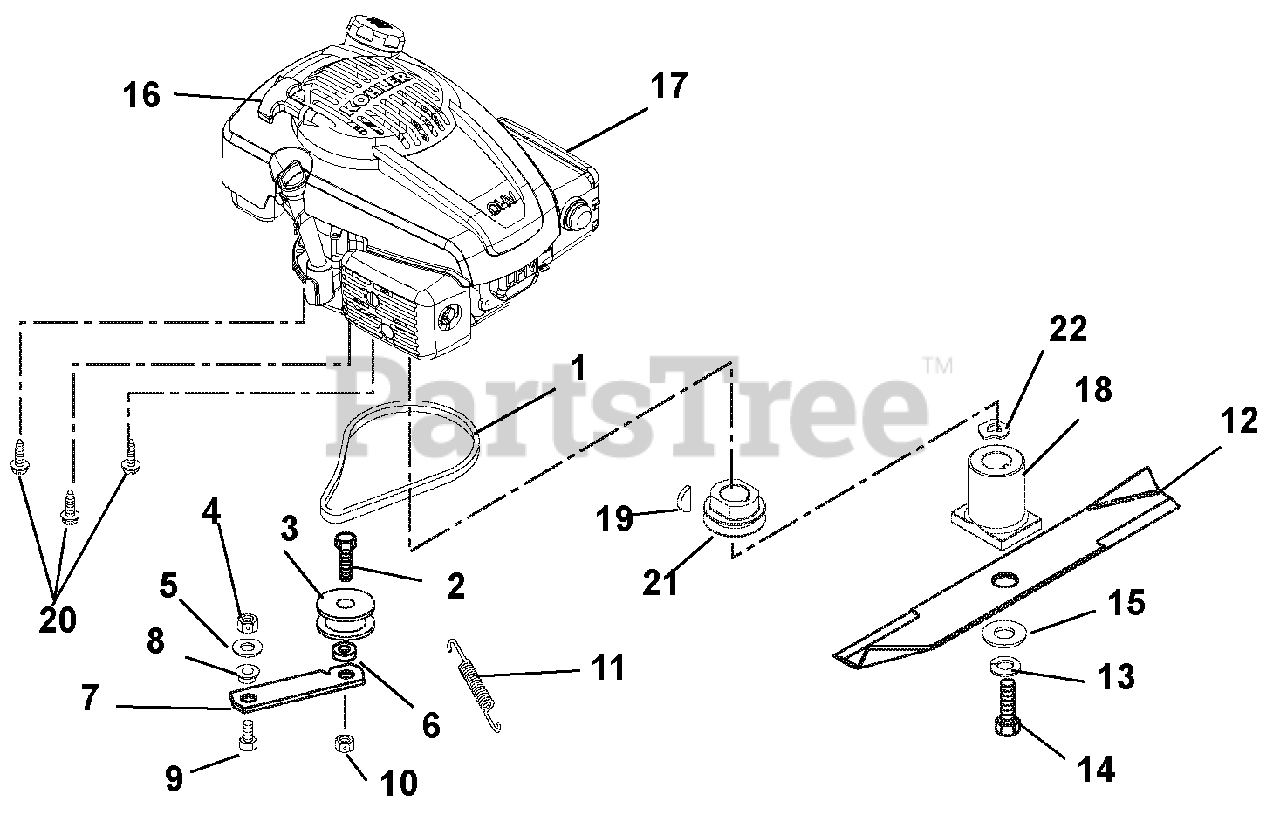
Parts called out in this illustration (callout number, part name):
1	V-Belt 3L Section
2	Bolt, Hex .44-14 x 1.50 Grade 5
3	Idler, Flat 1.75 x .47
4	Nut, Locking Center .31 -18
5	Washer, Flat Steel .344 x .688 x .065
6	Bushing, Sleeve .469 x .75 x .43
7	Idler Arm
8	Bushing, Flange .325 x .501 x .250 x 1.120
9	Bolt, Hex .31-18 x .75 Grade 5
10	Nut, Locking Center .44-14
11	Spring, Tension .043 x .44 x 3.31
12	Blade, 21" Mower
13	Washer, Locking .38 x .094
14	Bolt, Hex .38-24 x 2.00 Grade 8
15	Washer, Flat Steel .390 x 1.50 x .125
16	Recoil Start Handle
17	Engine, Kohler XT-7 (911260, 262, 264)
17	Engine, Kohler XT-7 CARB (911261, 263, 265)
17	Engine, Kawasaki 6.0hp Consumer (911136, 137)
18	Adapter, Blade
19	Key, Woodruff .156 x .625 x .25 SAE #6 (911136, 137, 262, 263, 264, 265)
20	Screw, Tapping .38-16 x 1.00 Hex Washer Head
21	Pulley, Sintered Iron (911136, 137, 262, 263, 264, 265)
22	Washer, Wave .885 x 1.311 x .125
